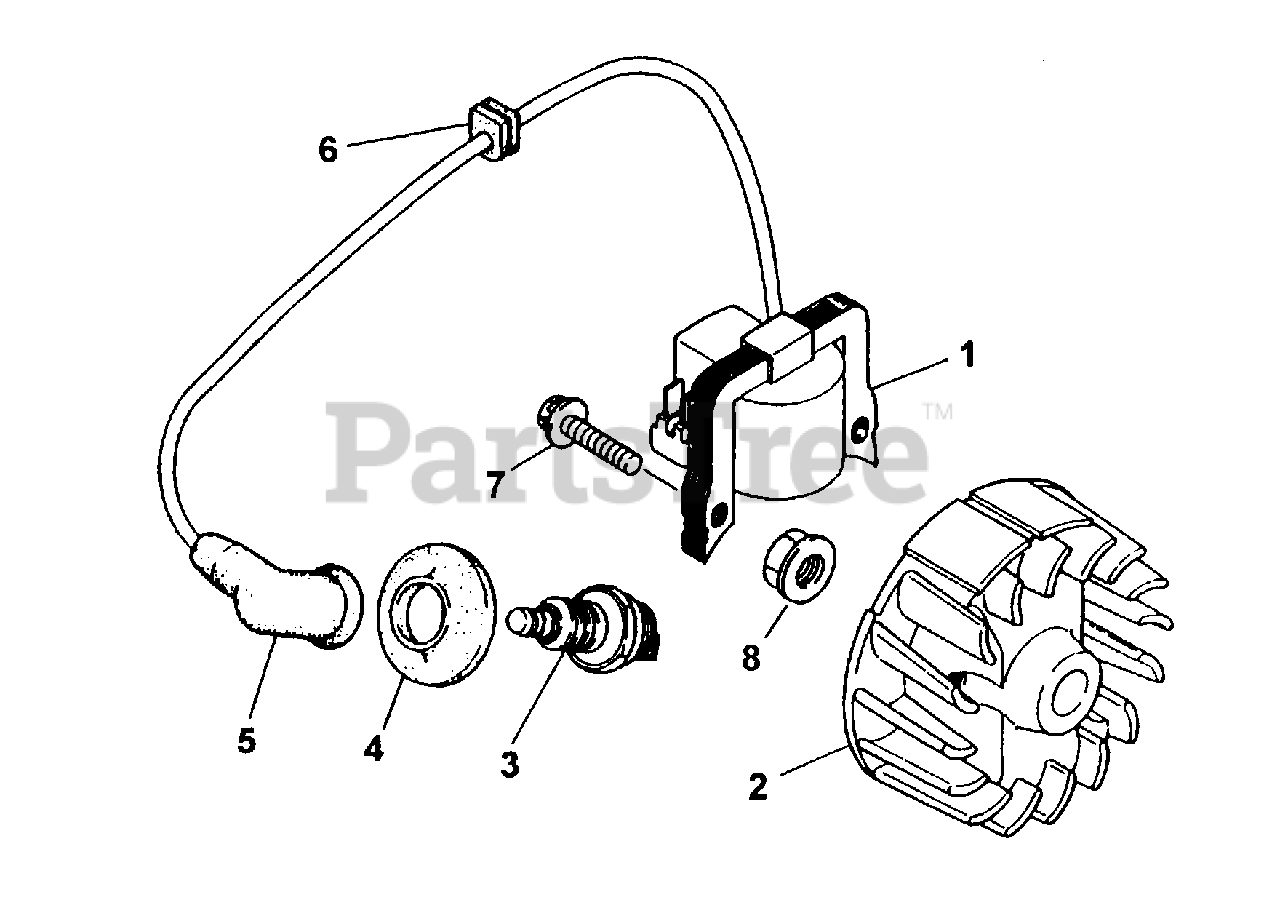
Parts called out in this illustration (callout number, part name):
1	COIL, IGNITION
2	ROTOR w/key
3	SPARK PLUG
4	CAP, GROMMET
5	CAP, PLUG
6	GROMMET, WIRE
7	BOLT & WASHER
8	NUT
